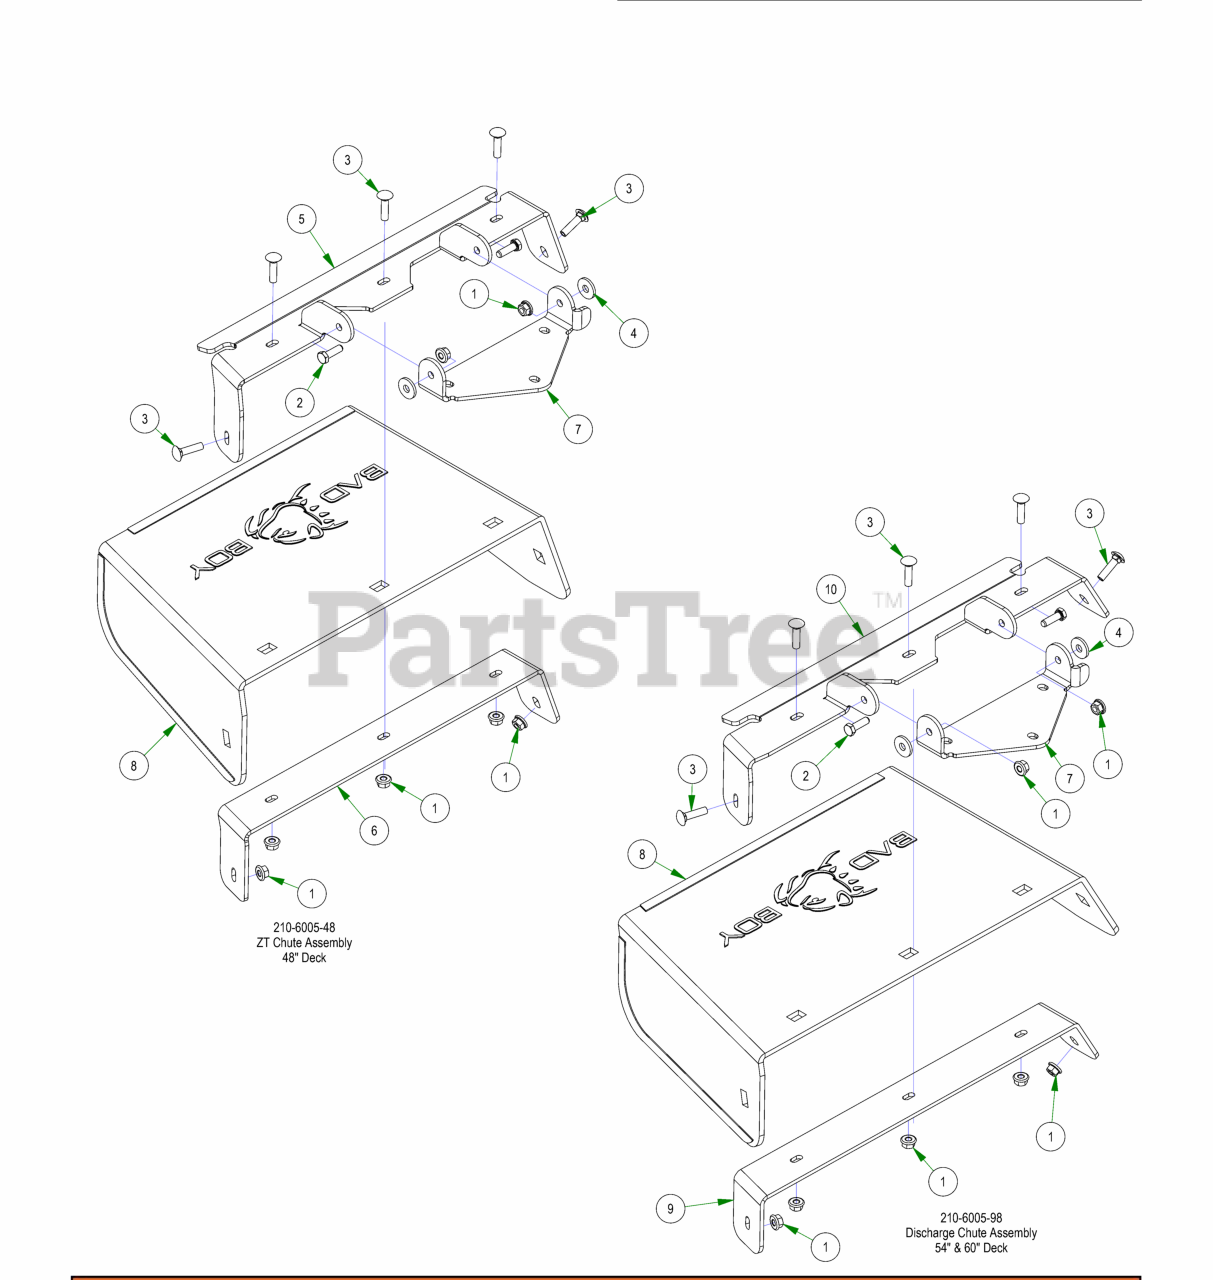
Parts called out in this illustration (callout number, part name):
1	5/16-18 NYLON INSERT FLANGE LOCKNUT ZINC
2	5/16-18 X 1 HEX CAP SCREW (GR.5) ZINC
3	5/16-18 X 1-1/4 CARRIAGE BOLT ZINC
4	.360 ID X .983 OD X .120 THICK FLAT WASHER NYLON
5	Discharge Upper Chute Bracket
6	Discharge Lower Chute Bracket
7	Discharge Chute Hanger (deck mounted)
8	Rubber Discharge Chute
9	60" Discharge Lower Bracket
10	60" Discharge Chute Upper Hanger
